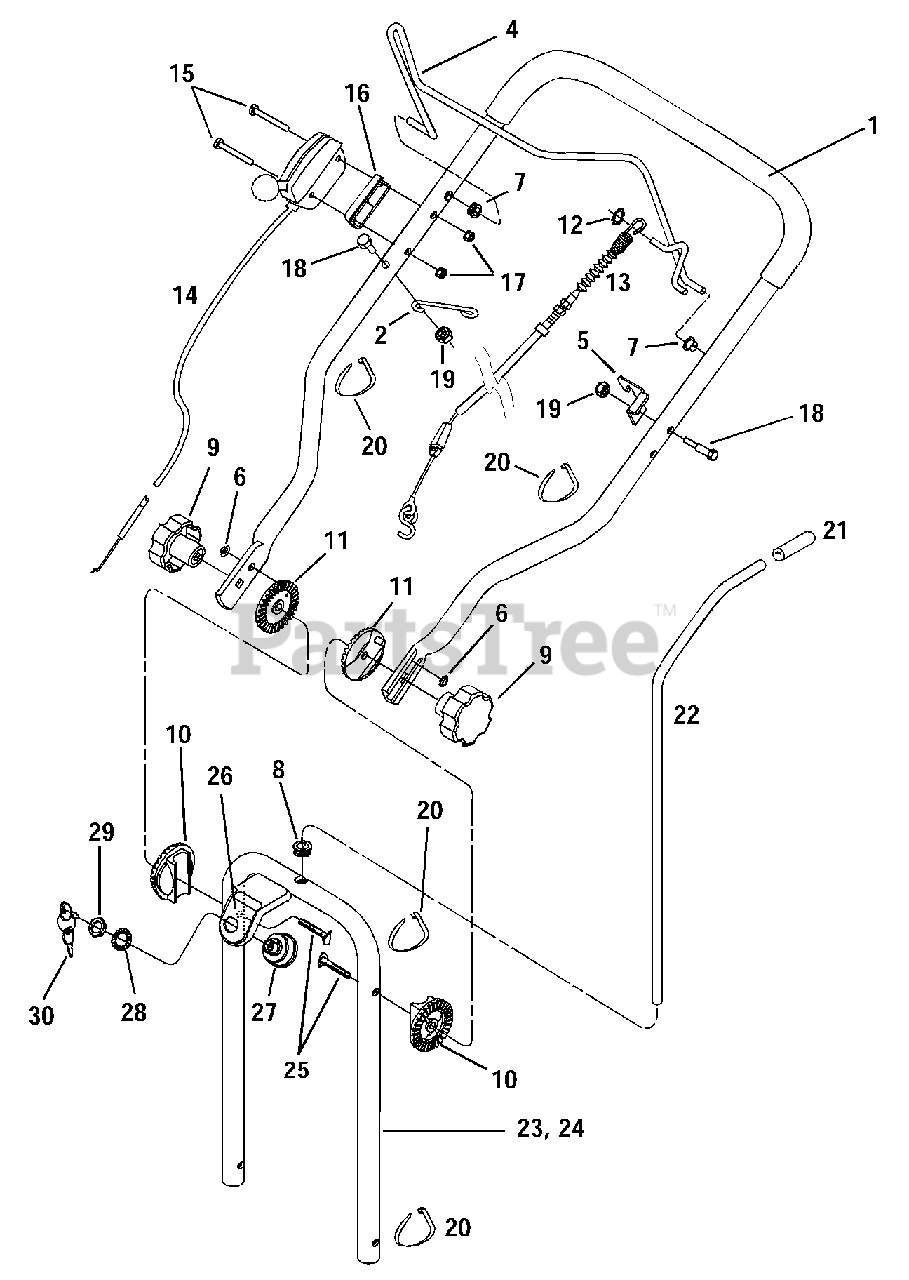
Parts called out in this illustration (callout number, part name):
1	Upper Handlebar w/sleeve
2	Rope Guide
5	Cable Bracket
6	Push-on Retainer
7	Nyliner Bushing
8	Nyliner Bushing
9	Adjusting Knob
10	Inside Hndlbr. Adj. Quadrant
11	Outside Hndlbr. Adj. Quadrant
12	Retaining Ring, External .312 I.D.
13	Control Cable
14	Throttle Cable
15	Screw, 10-24 x 2
16	Spacer
17	Lock Nut, 10-24
18	Hex Hd Screw, 1/4-20 x 1-1/8
19	Top Lock Nut, 1/4-20
20	Cable Tie
21	Steering Rod Grip
22	Upper Steering Rod
23	Lower Handlebar.
24	Lower Handlebar.
25	Curved Hd Bolt, 5/16-18 x 2
26	Decal-Keyswitch
27	Ignition Switch
28	Lockwasher, 5/8
29	Hex Nut, 5/8-32
30	Ignition Key
